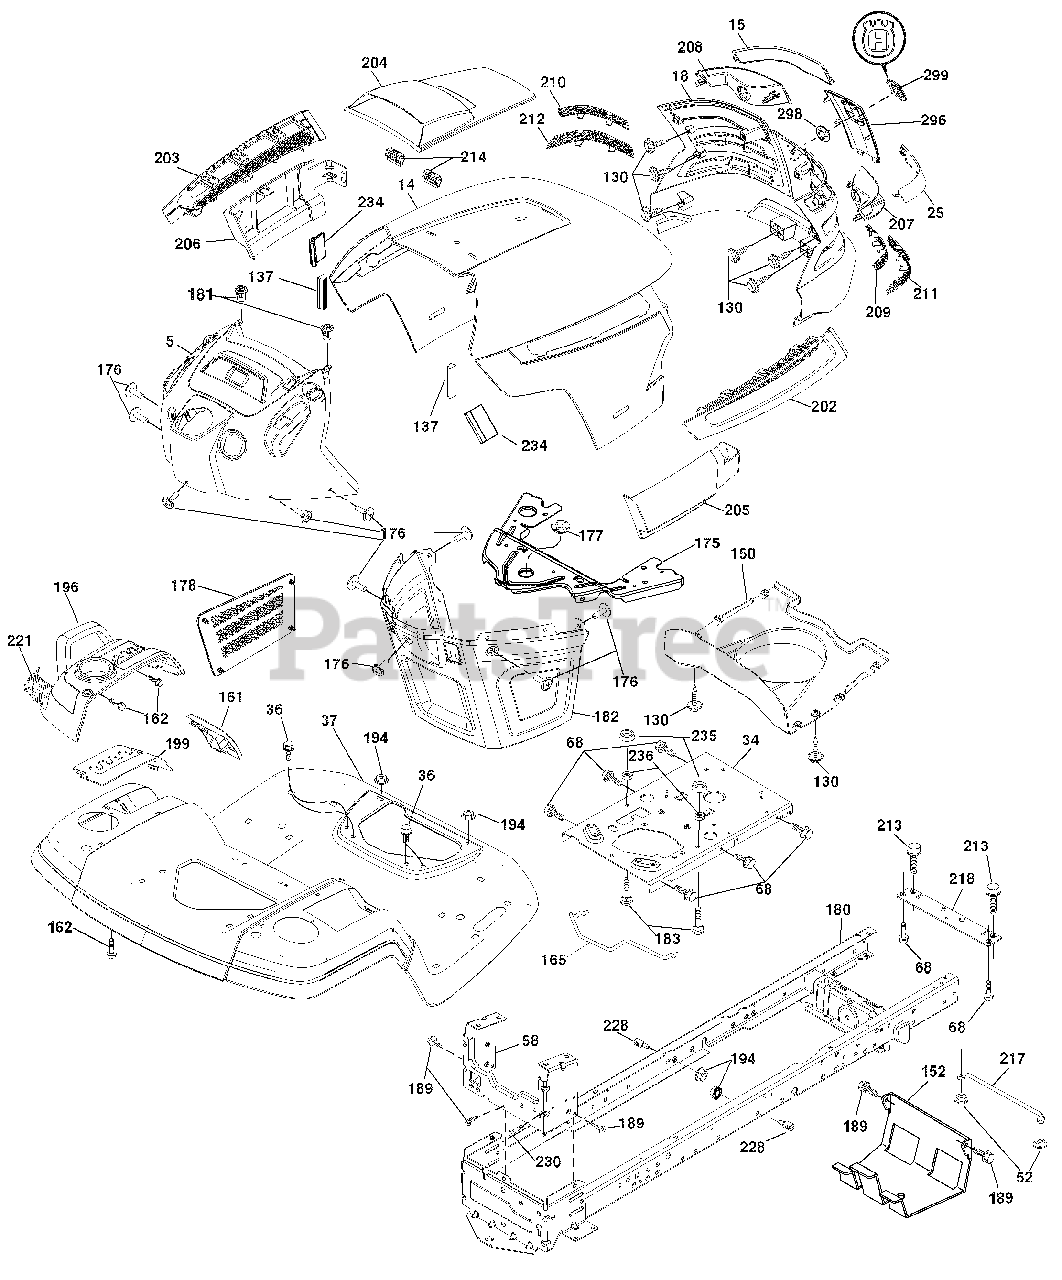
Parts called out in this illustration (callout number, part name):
14	Hood
18	Grille/Lens Asm.
34	Plate Engine
36	Screw 5/16-18 x 3/4
37	Fender
52	Nut Lock 5/16-18
58	Drawbar Lower
68	Screw Thdrol 5/16-18 x 1/2
130	Screw 10 x .750 BOS Thread
137	Bumper Dash
152	Shield Browning
159	Screw 3/8-16 x 3/4
161	Console Fuel Window
162	Screw Hex WSH HI-LO 1/4 x 1/2 unc
165	Support Tank Rear
175	Crossmember
176	Screw 10-24 x 5/8
177	Bushing Steering
178	Cargo Net Asm.
181	Bushing Mtg. Fender Crgo
182	Dash Lower
183	Bolt Fin Hex 5/16-18 unc x 1-1/4
189	Screw 5/16-18 x 3/4
194	Nut Lock Hex Flange 5/16-18
196	Console Asm. Deck Lift
199	Plate Deck Lift
202	Vent Side Hood RH
203	Vent Side Hood LH
204	Vent Top Hood
205	Skirt Hood Side RH
206	Skirt Hood Side LH
209	Insert Hex Top RH
210	Insert Hex Top LH
211	Insert Hex Bottom RH
212	Insert Hex Bottom LH
213	Bolt 5/16-18 x 3/4
214	Clip Retainer Tinner
218	X-Piece Hood Stop
221	Reflector LH
228	Stud Fastner
230	Bolt Shoulder 5/16-18
234	Bumper Hood
235	Spacer Fender
236	Nut Lock 5/16-18 unc
296	Trim, Husq.
299	Logo
